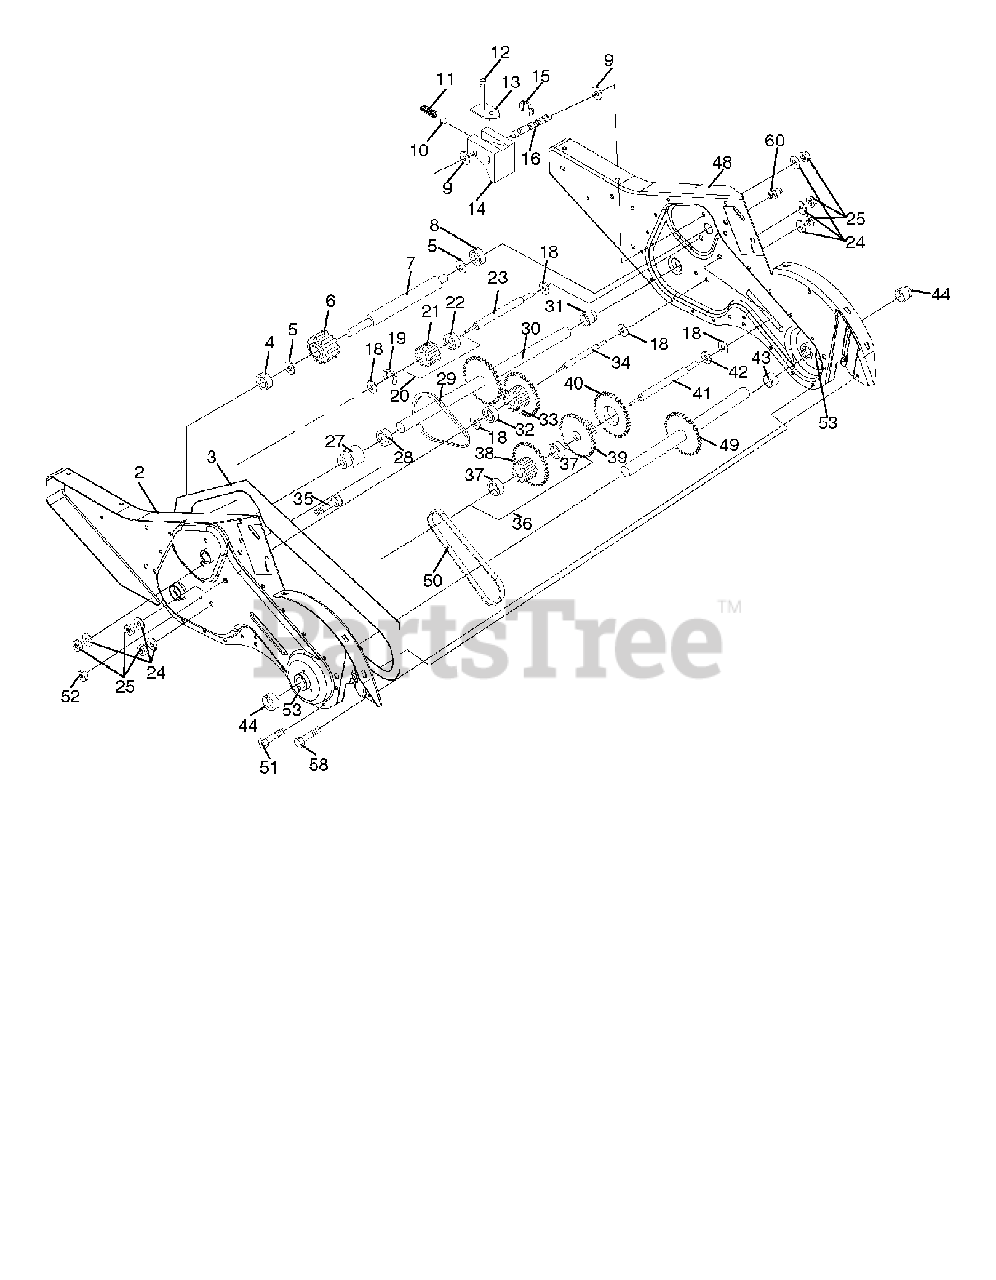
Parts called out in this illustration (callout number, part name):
2	GEARCASE.ASM.CRT.LH.W
3	GASKET.GEARCASE.CRT/DRT.TILLER
4	NEEDLE BRNG LT
5	THRUST WASHER
6	GEAR.PINION.INPUT
7	SHAFT.INPUT."D"".TILLER
9	WASHER, SEAL
11	SPRING-SHIFT CRT
12	O-RING TI
13	SHIFTING ARM
14	SHIFT FORK TI
15	KLIP RING
16	SHAFT.SHIFTER.TILLER
19	KLIP RING
20	GEAR ASSY CRT
21	GEAR-REV IDLR CRT
22	NEEDLE BEARING TI
23	SHAFT CRT
24	LOCKWASHER
25	NUT.ASF.HEX.7/16
27	BEARING, SHAFT LH CRT
29	CHAIN CRT
30	GROUND SHAFT ASS'Y
31	BEARING, SHAFT RH CRT
32	SPACER TI
33	SPRCKT 8 GEAR CRT
34	SHAFT.SECONDARY.REDUCTION.CRT
35	SCRW WHIZ LOK CRT
36	SPROCKET.ASM.W/BEARING.TILLER
39	GEAR TI
41	SHAFT.REDUCTION.TILLER
42	BRNG RACE T
43	SPACER TI
44	SEAL ASM, OIL
48	GEARCASE.ASM.CRT.RH.W/BEARING
49	SHAFT.ASM.TINE
50	CHAIN.TILLER
53	BEARING KIT
58	BOLT SHOULDER 1/4-20 UNC X.875
60	FITTING.GREASE.TAPERED
61	SPACER.1.015X1.50X.650
64	SPACER.1.015X1.50X.650
